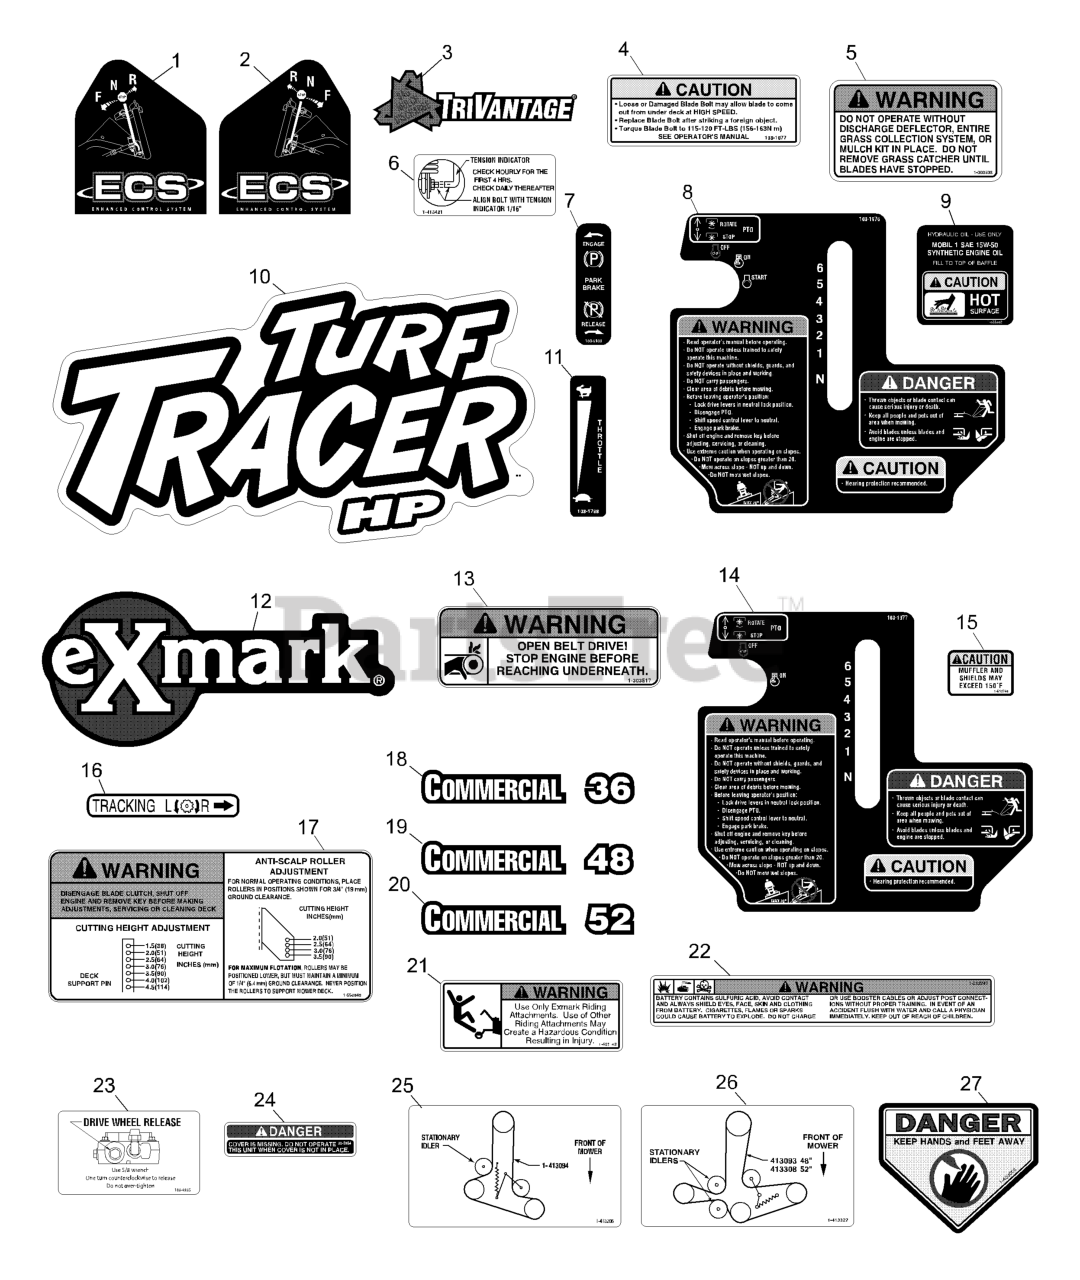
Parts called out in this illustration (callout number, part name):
1	DECAL,LH ECS INSTRUCTION
2	DECAL,RH ECS INSTRUCTION
4	DECAL,BOLT TORQUE
5	DECAL-WARNING, DISCHARGE
6	DECAL,INDICATOR
7	DECAL-BRAKE, PARK
8	DECAL,CONSOLE
10	DECAL,TTHP MODEL
11	DECAL,THROTTLE ONLY
12	DECAL,EXMARK LOGO
13	DECAL,BELT DRIVE
14	DECAL,ECS CONSOLE
16	DECAL,TRACKING ADJUST
17	DECAL,ANTI SCALP
18	DECAL,COMMERCIAL 36
19	DECAL,COMMERCIAL 48
20	DECAL,COMMERCIAL 52
21	DECAL,SULKY WARNING
22	DECAL-BATTERY
23	DECAL,DRIVE RELEASE
24	DECAL-COVER, MISSING
25	DECAL,BELT ROUTING
26	DECAL,BELT ROUTING
27	DECAL-DANGER
